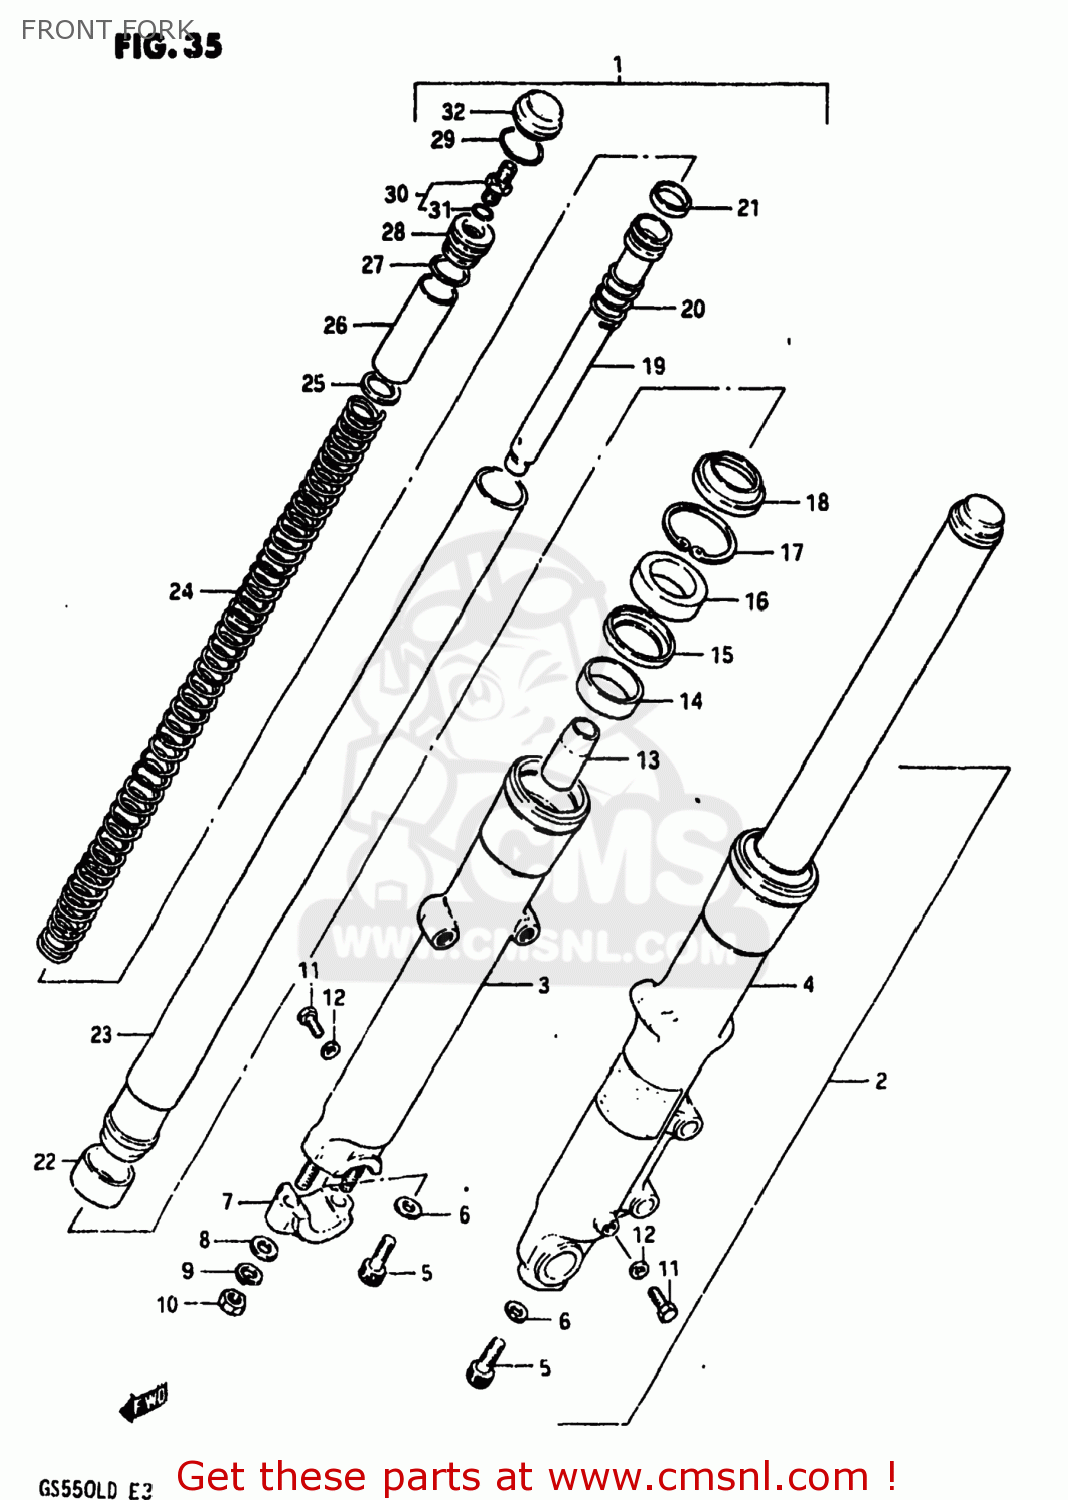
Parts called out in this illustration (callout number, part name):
1	DAMPER ASSEMBLY,RIGHT
2	DAMPER ASSEMBLY,LEFT
3	TUBE,FORK,OUTER,RIGHT
4	TUBE,FORK,LEFT,OUTER
5	BOLT(8X27)
6	GASKET (NAS)
7	HOLDER,AXLE,RIGHT
8	WASHER
9	LOCK WASHER
10	NUT (8MM)
11	BOLT
12	GASKET,DRAIN,PLUG (NAS)
13	PIECE,OIL LOCK
14	BUSHING,GUIDE
15	SPACER,SEAL
16	OIL SEAL,FRONT FORK
17	CIRCLIP,INNTERNAL
18	SEAL,DUST
19	CYLINDER,FRONT FORK
20	SPRING
21	RING,PISTON
22	PISTON
23	TUBE,INNER
24	SPRING
25	SPRING,JOINT
26	SPACER,SPRING
27	O RING
28	GUIDE,SPRING
29	RING,STOPPER
30	VALVE,AIR
31	O-RING
32	CAP,FR FORK
